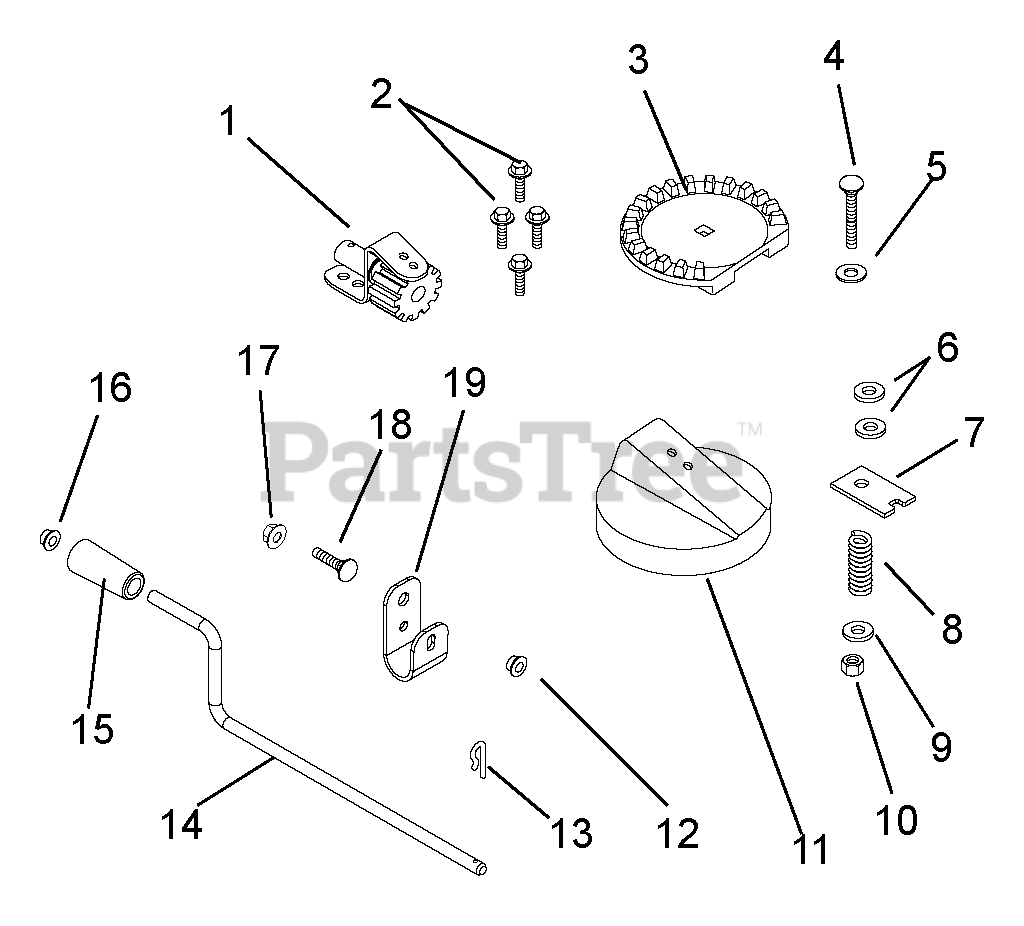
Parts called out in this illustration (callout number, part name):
1	BRACKET W/PINION GEAR
2	@SCR-TAP .25-20X.50 HWH TR YWZ
3	CHUTE GEAR
4	@BLT-RDHDSQNK .38-16X2.50 G5YZ
5	WSHR-FL-STL .380X1.50X.062 YWZ
6	FRICTION WASHER
7	PLATE, FRICTION
8	SG-COMP .187X.56X1.62
9	@WSHR-FL-STL.406X.812X.065 YWZ
10	@NUT-LK-CTR .38-16 YWZC
11	GEAR COVER
12	BUSHING, POLYLINER-.38 SNAPIN
13	PIN, SPRING CLIP
14	ROD, CHUTE CRANK
15	KNOB, CHUTE CRANK
16	CAP, 3/8 ROD YWZC
17	@NUT-LK-TOP-FLG .31-18 YWZC
18	@BLT-RDHDSQNK .31-18X1.75 G5YZ
19	BRACKET, CRANK SUPPORT
